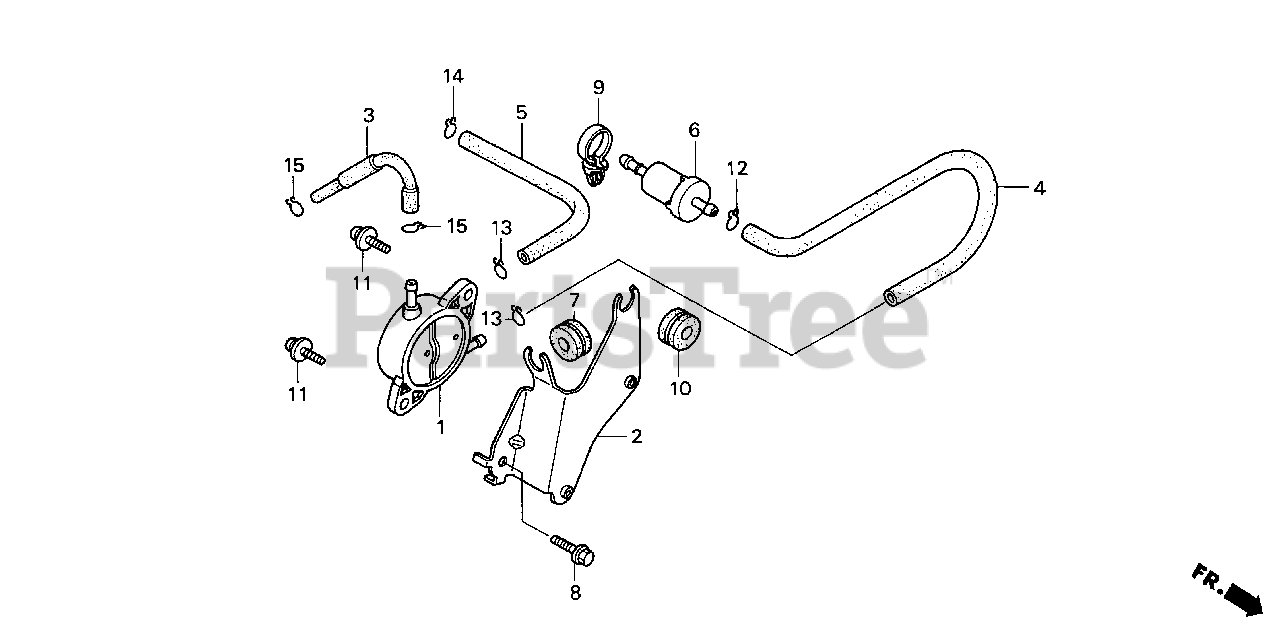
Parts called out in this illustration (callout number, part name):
1	PUMP ASSY., FUEL
2	STAY, FUEL PUMP
3	TUBE, FUEL
4	TUBE B, FUEL
5	TUBE, DIAPHRAGM
6	FILTER, FUEL
7	GROMMET, RESERVE TANK
8	BOLT, FLANGE (6X14)
9	CLIP, WIRE HARNESS
10	GROMMET, PUMP STAY
11	SCREW-WASHER (6X16)
12	CLIP, TUBE (B8)
13	CLIP, TUBE (B10)
14	CLIP, TUBE (C9)
15	CLIP, TUBE (C11)
